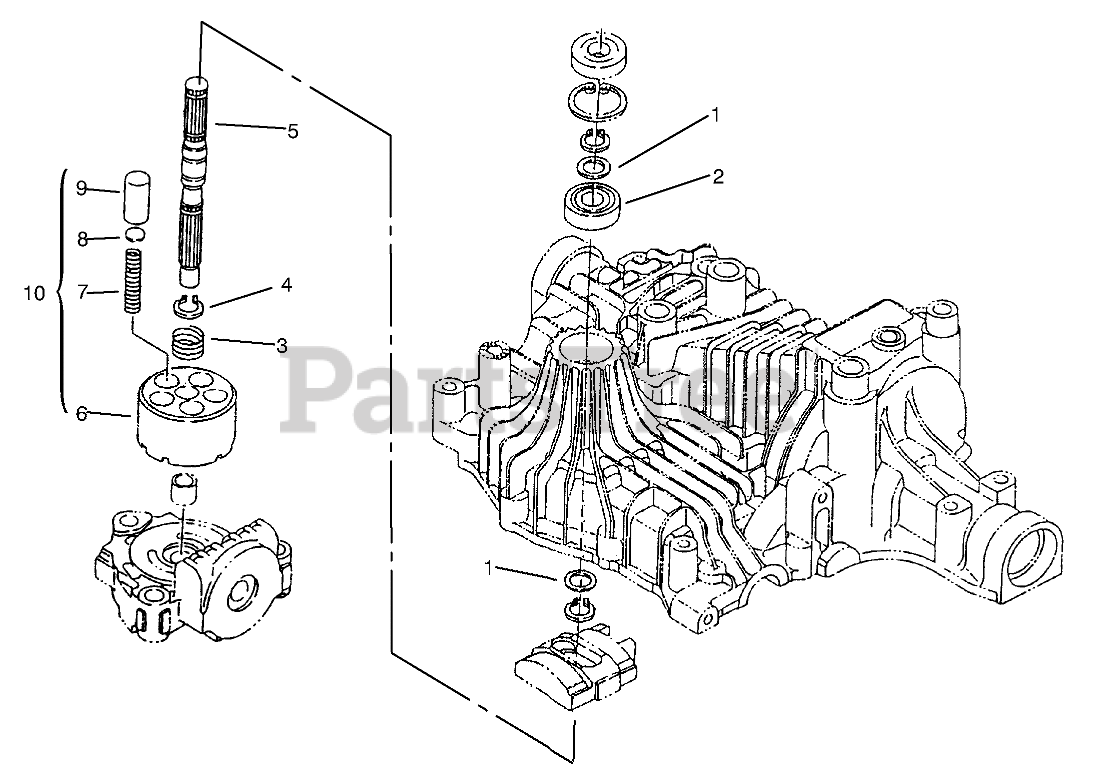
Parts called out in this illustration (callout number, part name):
1	WASHER
2	BEARING-BALL
3	SPRING
4	RING-SNAP
5	SHAFT - PUMP
6	Block-Cylinder
8	Washer
10	ASM - CYCLINDER INC 6-9
